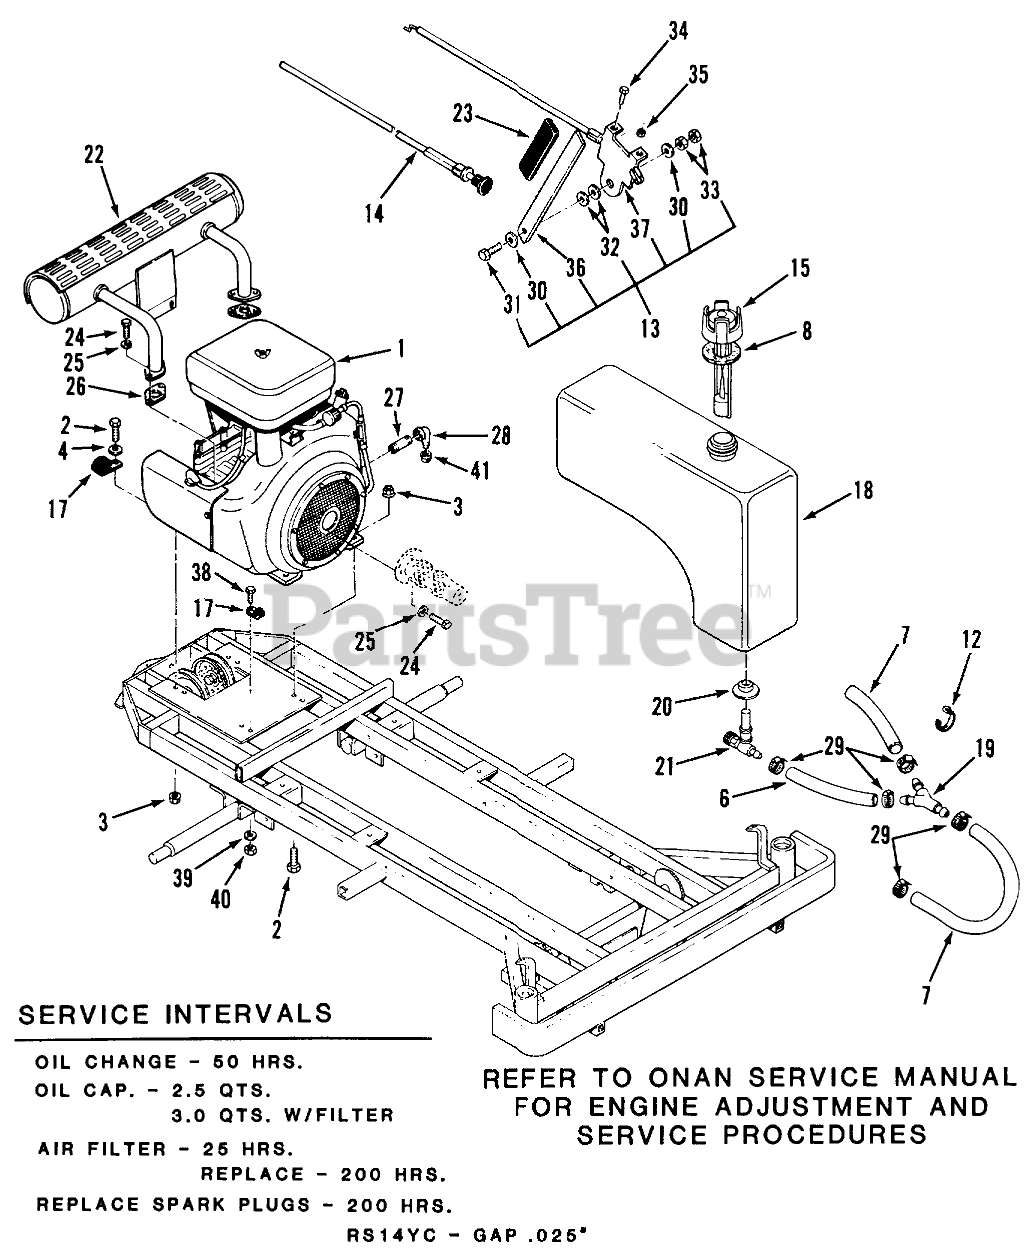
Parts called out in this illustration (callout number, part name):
1	Engine-24 HP Onan (T260G-GA024 Spec. No. 4404F).
2	BOLT
3	NUT
4	Washer
6	Hose5"
7	Fuel Line (29.5")
8	GASKET-GAS CAP
12	TIE-PLASTIC
13	Throttle Control (includes items 30 thru 33, 36 and 37)
14	CABLE-CHOKE
15	Fuel Gauge Cap w/o Screw Vent (includes item 8).
17	CLIP
18	Fuel Tank (includes items 20 & 21)
19	FITTING-FUEL 45-Y
20	BUSHING
21	VALVE-FUEL
22	Muffler
23	GRIP BRAKE20258-K
24	Bolt
25	Lockwasher
26	Exhaust Gasket
27	Pipe
28	STREET-ELBOW 90 DEG
29	Clamp
30	HHCS
31	HHCS
32	WASHER NYLON
33	LOCKNUT 5/16-18GR.B
34	Screw-Machine
35	Nut
36	HANDLE-THROTTLE B
37	CABLE-THROTTLE
38	Bolt
39	WASHER 5/16 SAE
40	Nut
41	Cap
